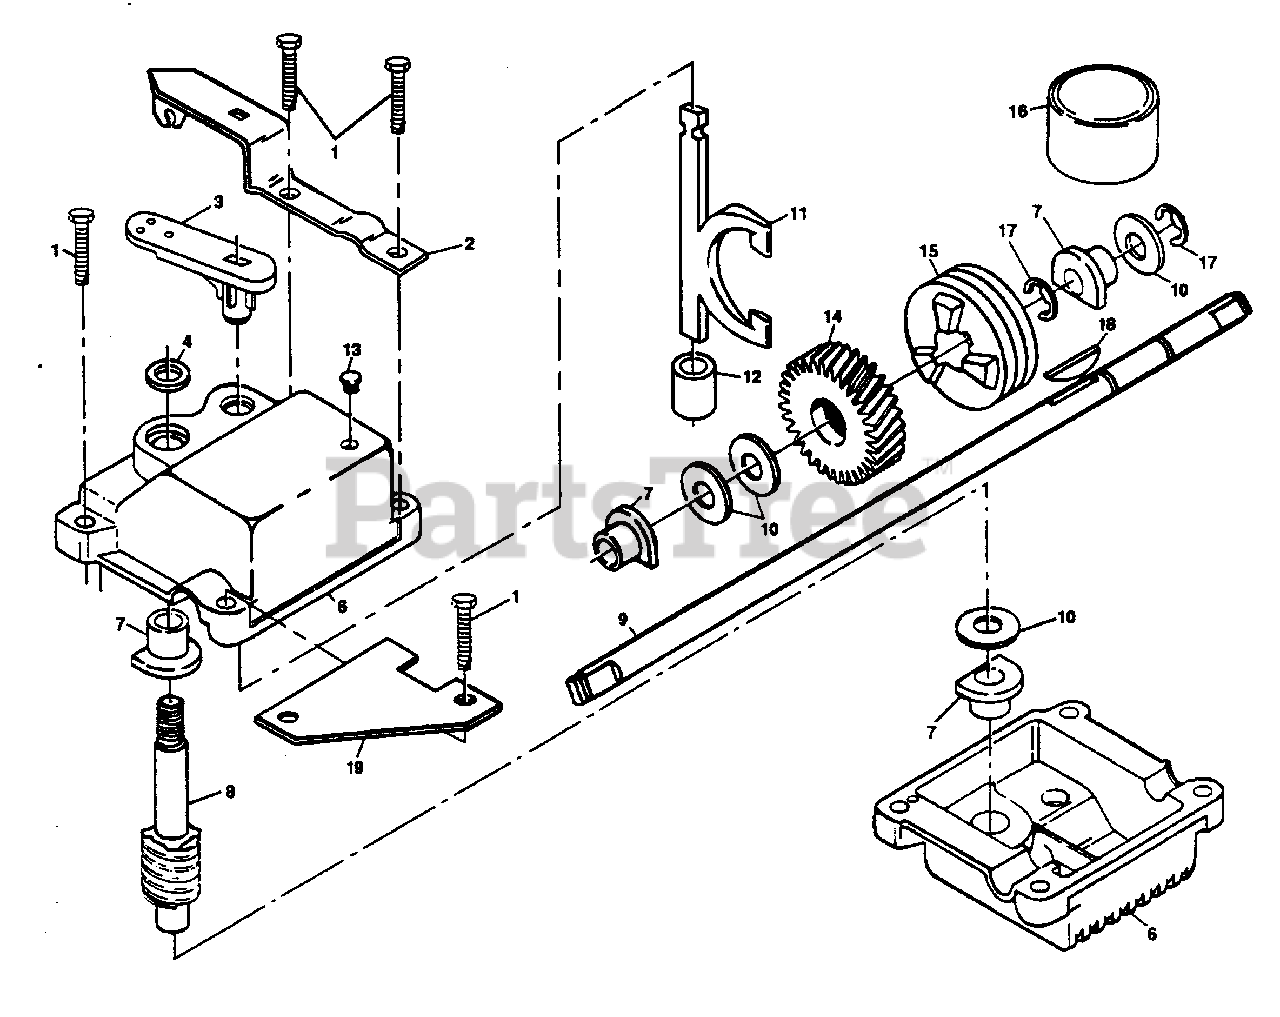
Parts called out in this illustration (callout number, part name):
1	Screw, Tapping 1/4-20 x 1-1/4 (AYP part number)
2	Bracket, Adjusting (AYP part number)
3	Shifter (AYP part number)
6	Gear Case Halves, Upper and Lower (Includes Key #4, 5 and 7) (AYP part number)
8	Shaft, Worm (AYP part number)
9	Drive Shaft (AYP part number)
10	Washer, Hardened (AYP part number)
11	Yoke, Clutch (AYP part number)
12	Bushing (AYP part number)
13	Plug (AYP part number)
14	Gear, Helical (AYP part number)
15	Jaw, Clutch (AYP part number)
16	Grease (AYP part number)
18	Key, Hi-Pro (AYP part number)
19	Spring Bracket (AYP part number)
